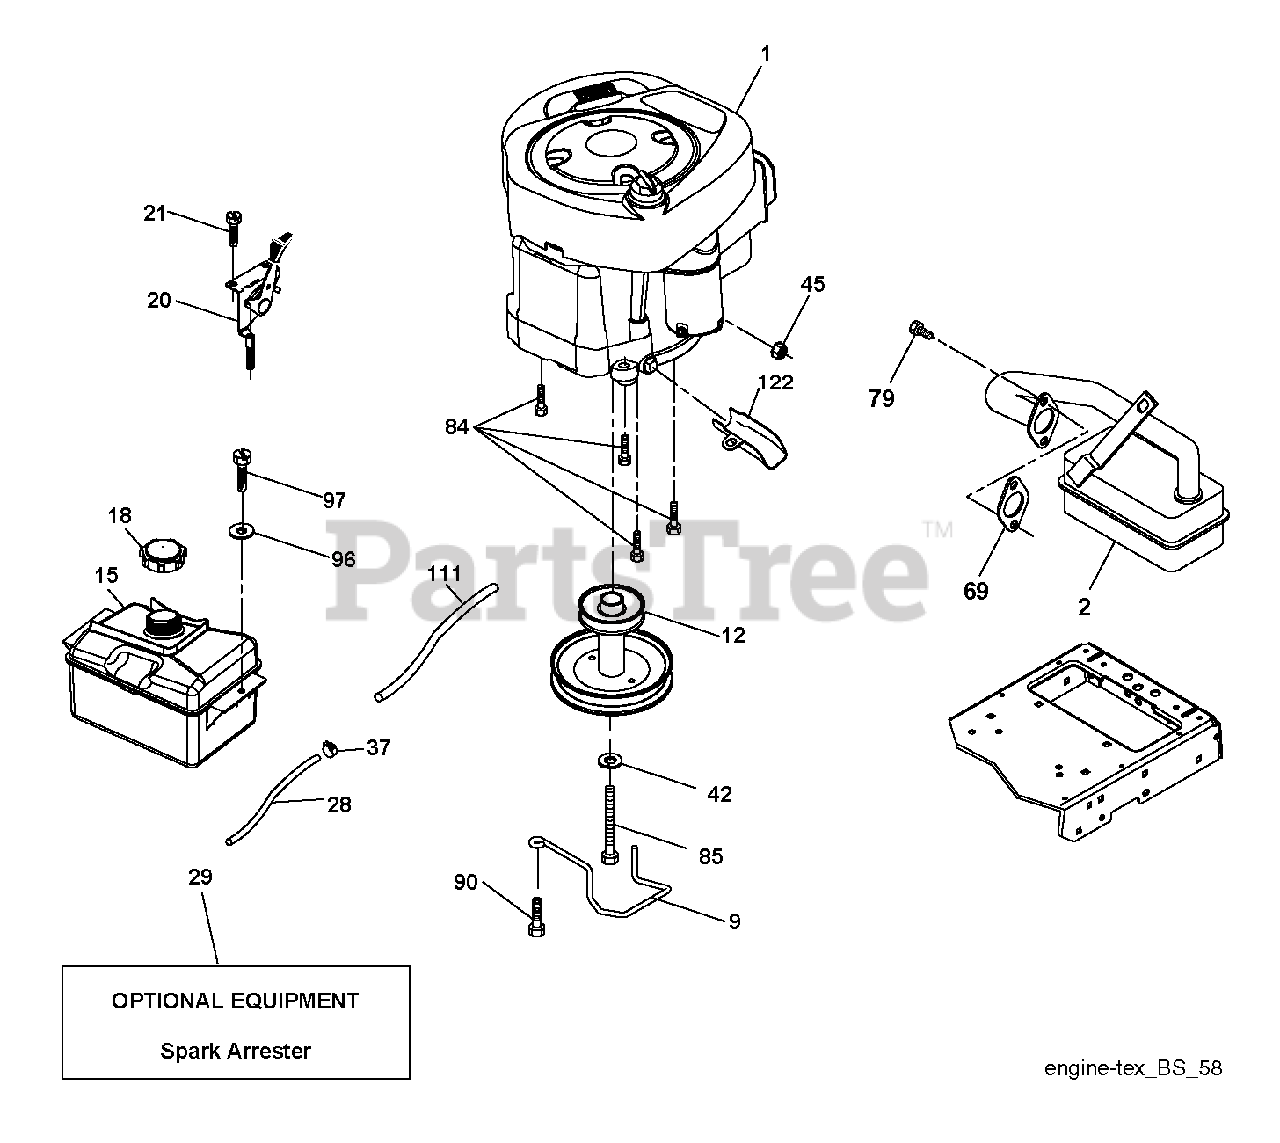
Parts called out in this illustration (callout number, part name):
2	MUFFLER.LT.BRIGGS.14HP.IC/OHV
9	KEEPER.BELT.ENGINE.4.2
12	PULLY ENGINE
15	TANK.ASM.1.5GAL.FRT.W/CAP.EPA
18	CAP.2.25'.VENTED.RATCHET.EPA
21	SCREW.#10 X 0.750.BOS (2 2)
28	LINE.FUEL.20"FRONT.EMI
29	SPARK ARRESTOR KIT
37	HOSE CLAMP
42	LOCKWASHER
45	NUT
79	SCREW.SOCKET HD.5/16-1
84	SCREW.3/8-16
85	BOLT HEX 7/16-20X4-1/4"
90	SCREW 3/8-16X1
97	SCREW HEXWSHR 1/4-20X3/4
111	RP PURGE LINE
122	EXTENSION DRAIN OIL
